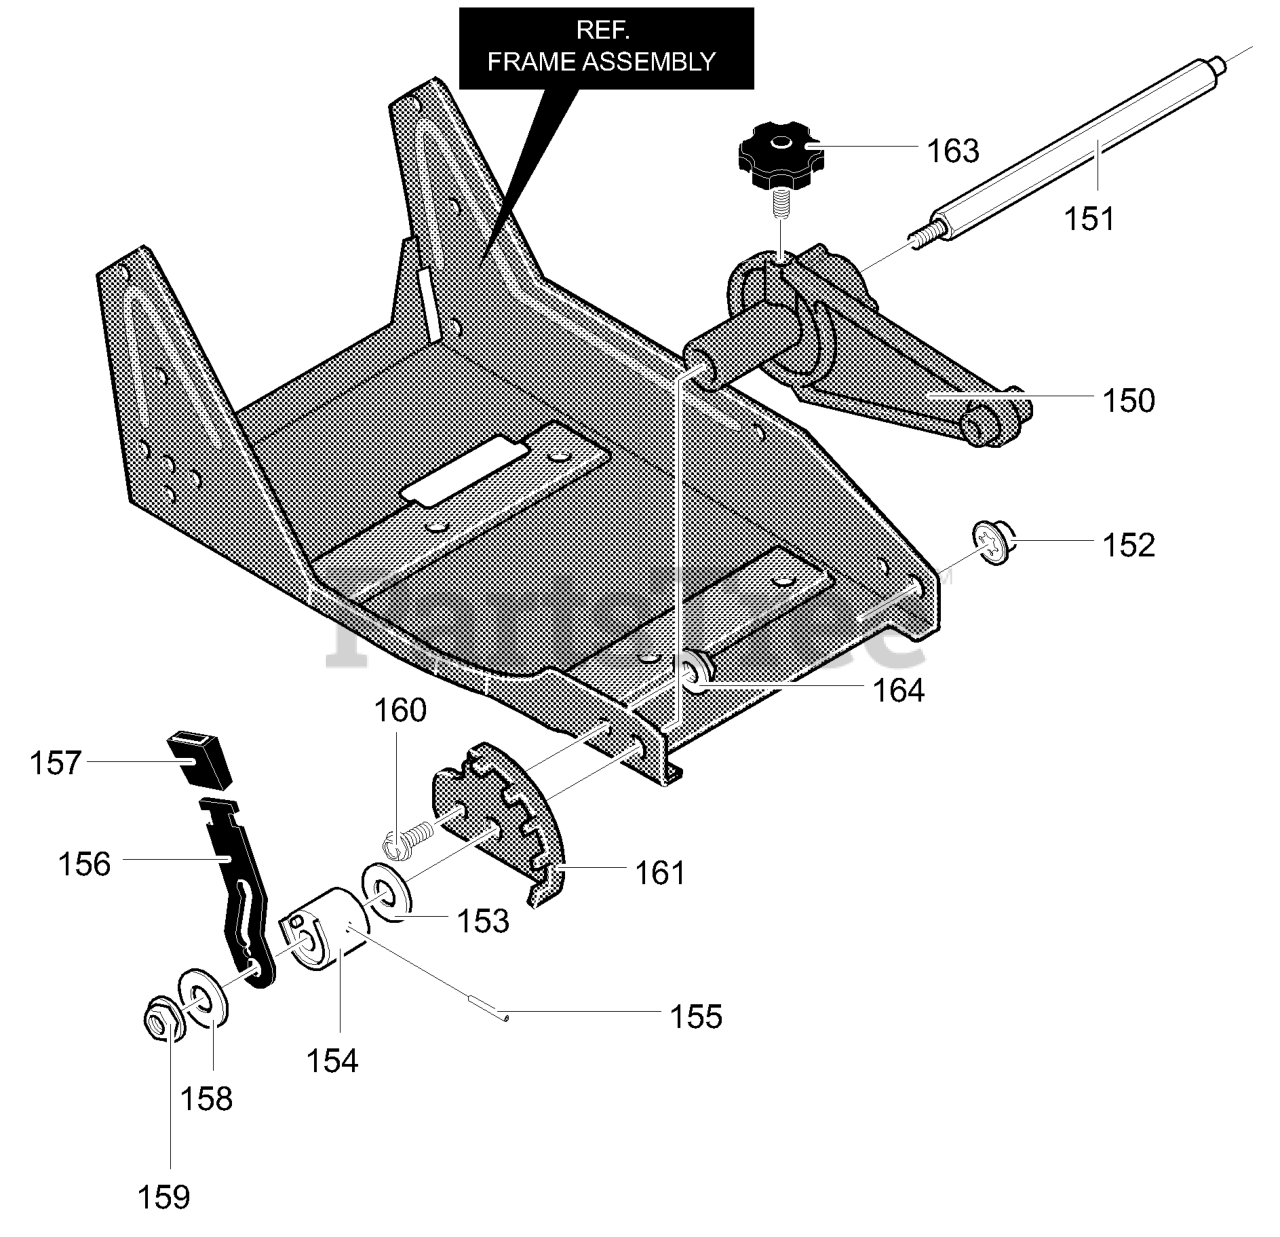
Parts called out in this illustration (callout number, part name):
150	Front Wheel Arm
151	Front Curb Hopper
152	Pushnut, Washer
153	Plastic Washer
154	Spacer, Height Adjust
155	Pin, Spring
156	Lever, Height Adjust
157	Knob, Rectangle
158	Flatwasher
160	Screw, 5/16-18 x 0.63
161	Plate, Height Adjust
163	Knob, Molded
164	Nut, 5/16-18
